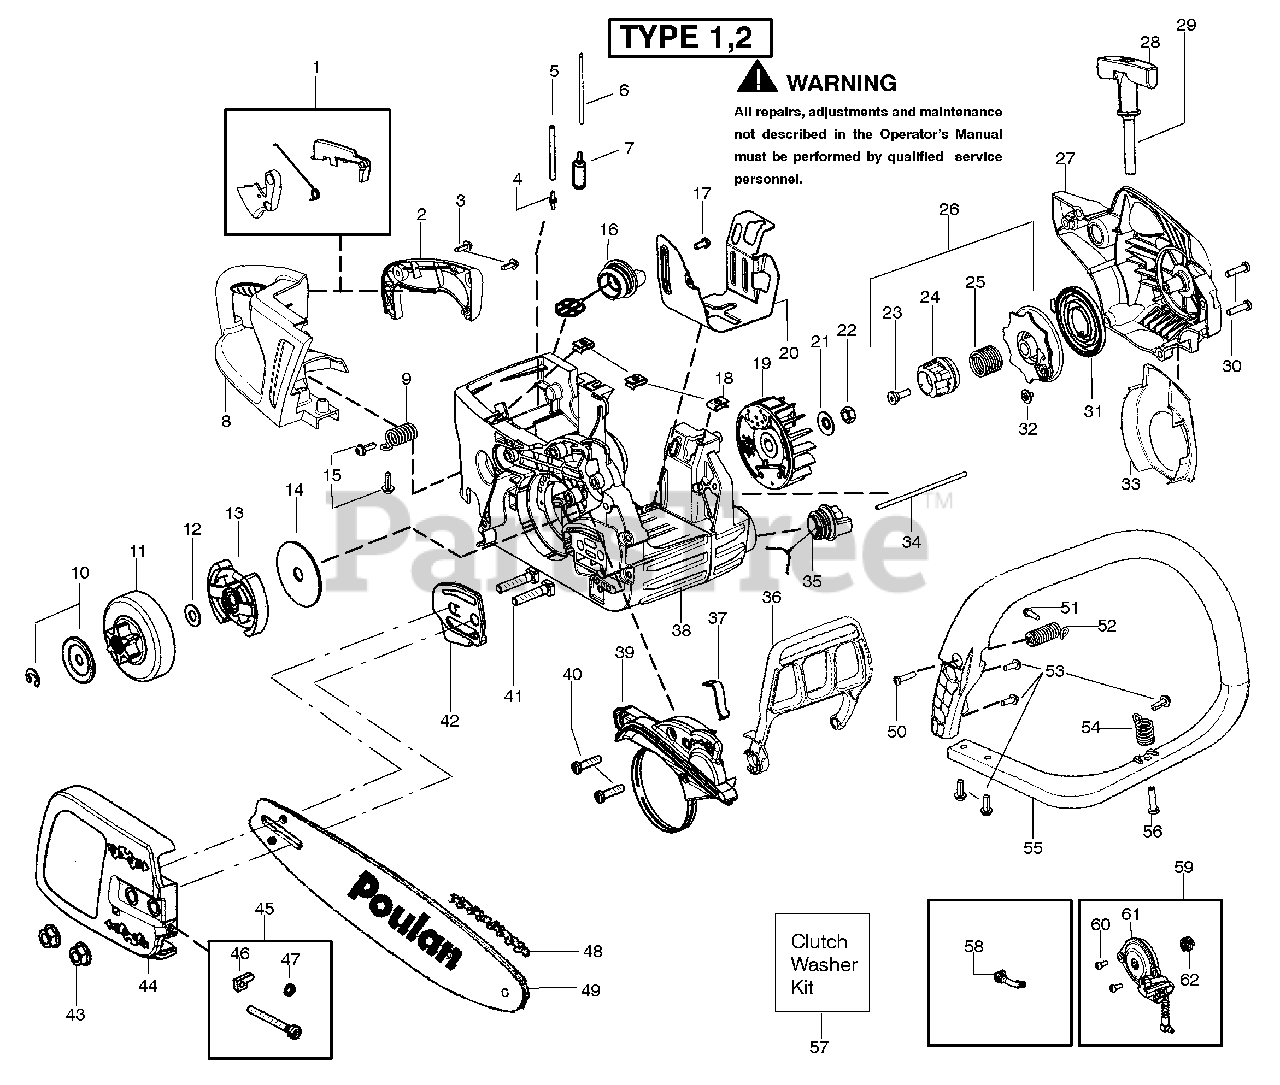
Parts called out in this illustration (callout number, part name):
1	Kit-Trigger/Lockout
2	Cover-Handle
4	Fitting-Fuel Line
5	Kit-Fuel Line
6	Kit-Fuel Line
7	Assy-Fuel Pick Up
8	Handle-Rear
9	Spring-Rear Isolator
10	Kit-Clutch Washer
11	Assy-Clutch Drum 3/8"
12	Kit-Clutch Washer
13	Assy-Clutch
14	Washer-Large Clutch
16	Assy-Fuel Cap w/ret
18	Nut-"U" type speed
19	Assy-Flywheel
20	Shield-Heat
21	Washer-Flywheel
22	Nut-Flywheel
23	Screw-Shoulder
24	Starter Hub-EPS
25	Spring-EPS
26	Kit- EPS Starter Pulley
27	Housing-Fan
28	Handle-Starter
29	Kit-Rope
31	Spring-Starter
34	Assy-Oil Vent
35	Assy-Oil Cap w/ret.
36	Handguard
37	Spring-Handguard
38	Assy-Chassis
39	Kit-Chainbrake
41	Bolt-Bar
42	Plate-Bar
44	Assy-Clutch Cover
45	Kit-Bar Adjust
46	Pin-Bar Adjust
47	Retainer-Bar Adjust
48	Accy-18" Chain
49	Accy-18" Bar
52	Assy-Rear Iso. Spring
54	Assy-Front Iso. Spring
55	Handle-Front
57	Kit-Clutch Washer
58	Assy-Oil Pick Up
59	Kit-Oil Pump
61	Assy-Oil Pump
62	Gear-Worm
